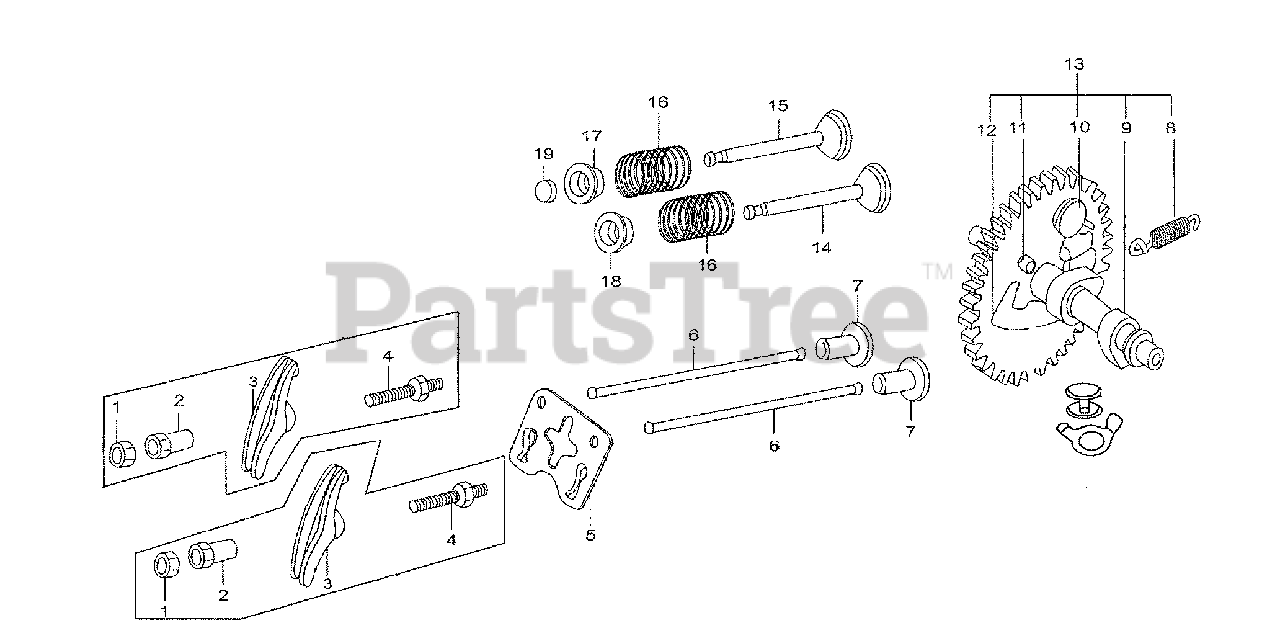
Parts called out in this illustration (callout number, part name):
1	NUT, PIVOT ADJUSTING
2	PIVOT, ROCKER ARM
3	ARM, VALVE ROCKER
4	BOLT, PIVOT
5	LIMIT POSITION PANEL
6	ROD, PUSH
7	LIFTER VALVE 8 X 35
8	SPRING, WEIGHT RETURN
11	SPRING, HANG PIN
12	AUTO-REDUCTOR SUBASSEMBLY
13	CAM SHAFT ASSY INCLD(8,9,10,11,12)
14	VALVE, INLET
15	VALVE, EXHAUST
16	SPRING, VALVE
17	RETAINER, EXH VALVE SPRING
18	RETAINER, INLET VALVE SPRING
19	ROTATOR, VALVE
